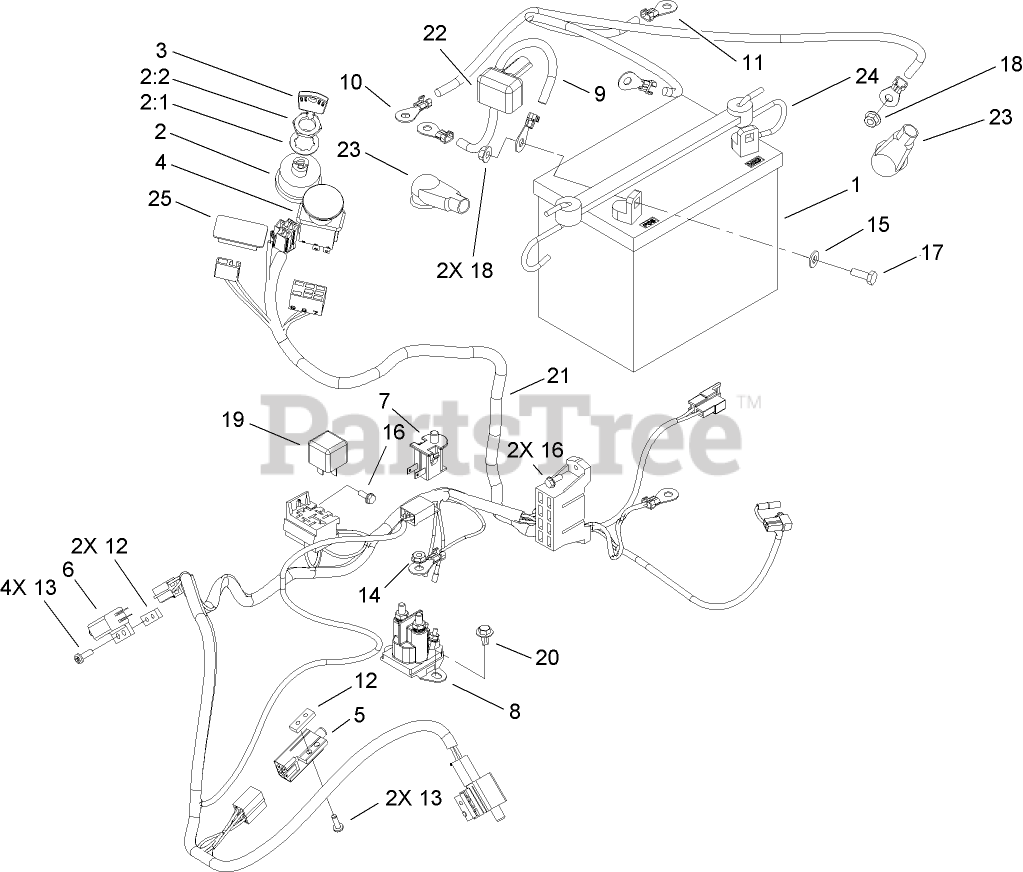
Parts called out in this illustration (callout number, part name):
2	SWITCH ASM
2:1	NUT-HH
2:2	WASHER-LOCK
3	KEY-IGNITION
4	SWITCH-PTO,ON-ON-NONE
6	SWITCH-OPEN, NORMALLY
7	SWITCH-BAIL
8	SOLENOID-STARTER
9	WIRE ASM
10	WIRE ASM
11	CABLE
12	PLATE-TAPPED
13	SCREW-PPHTF
14	NUT-KEPS
15	WASHER-FLAT
16	SCREW-TAPTITE
17	SCREW-HH
18	NUT-HF
19	RELAY
20	SCREW-HHFTF
21	HARNESS-WIRE
22	BOOT-TERMINAL
23	BOOT-INSULATOR, TERMINAL
24	HOLDDOWN-BATTERY
25	PLUG-HOLE
